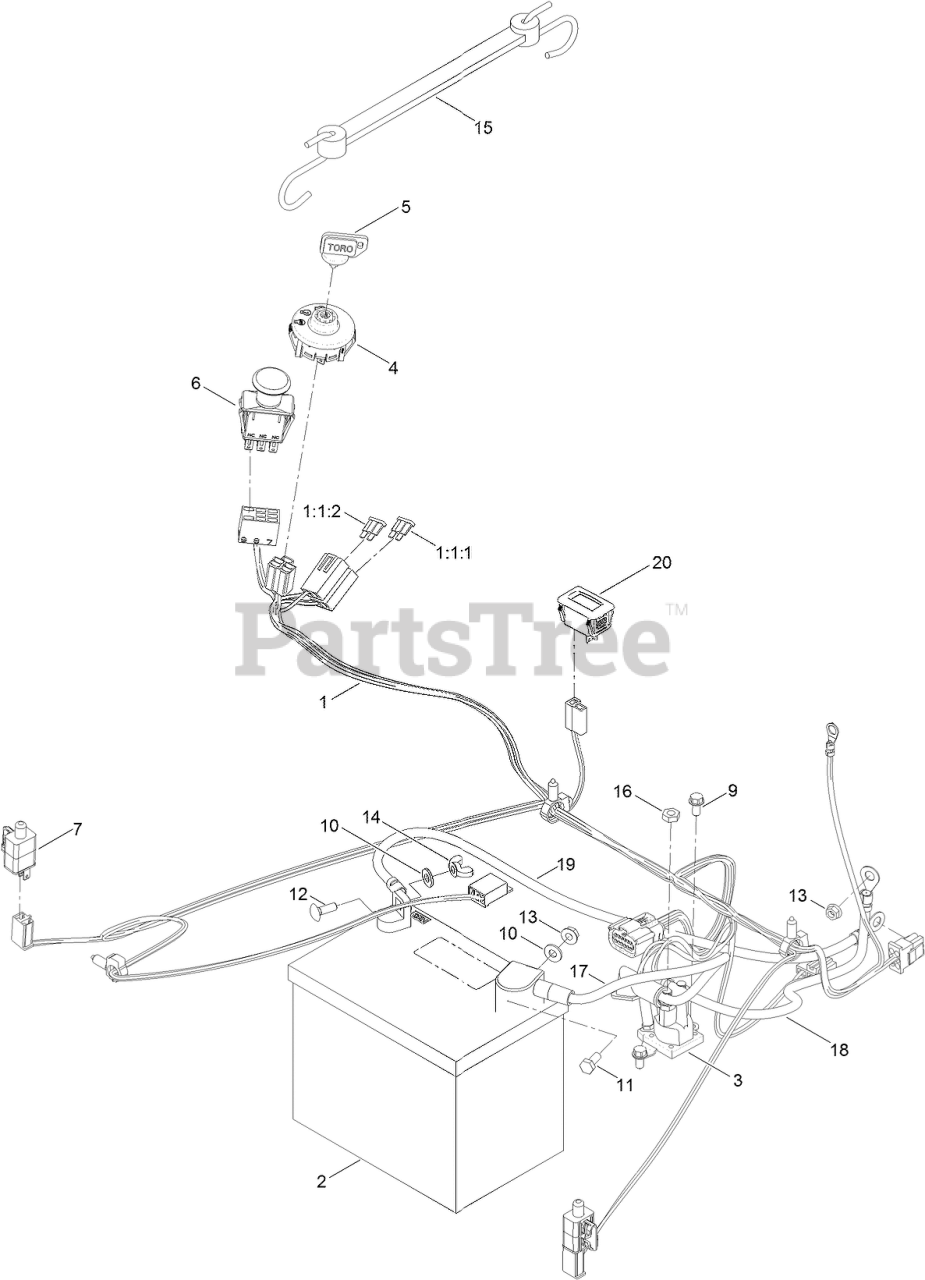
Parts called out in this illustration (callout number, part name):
1	HARNESS-WIRE
1:1:1	FUSE-BLADE, 30 AMP
1:1:2	FUSE-BLADE, 25 AMP
2	BATTERY
3	SOLENOID
4	SWITCH-IGNITION
5	KEY-IGNITION
6	SWITCH-PTO
7	SWITCH
9	SCREW-HWH
10	WASHER-FLAT
11	SCREW-HH
12	BOLT-CARR
13	NUT-HF
14	NUT-WING
15	HOLDDOWN-BATTERY
16	NUT-JAM
17	CABLE-BATTERY, RED
18	CABLE-BATTERY, POSITIVE
19	CABLE-BATTERY, BLACK
20	HOURMETER
